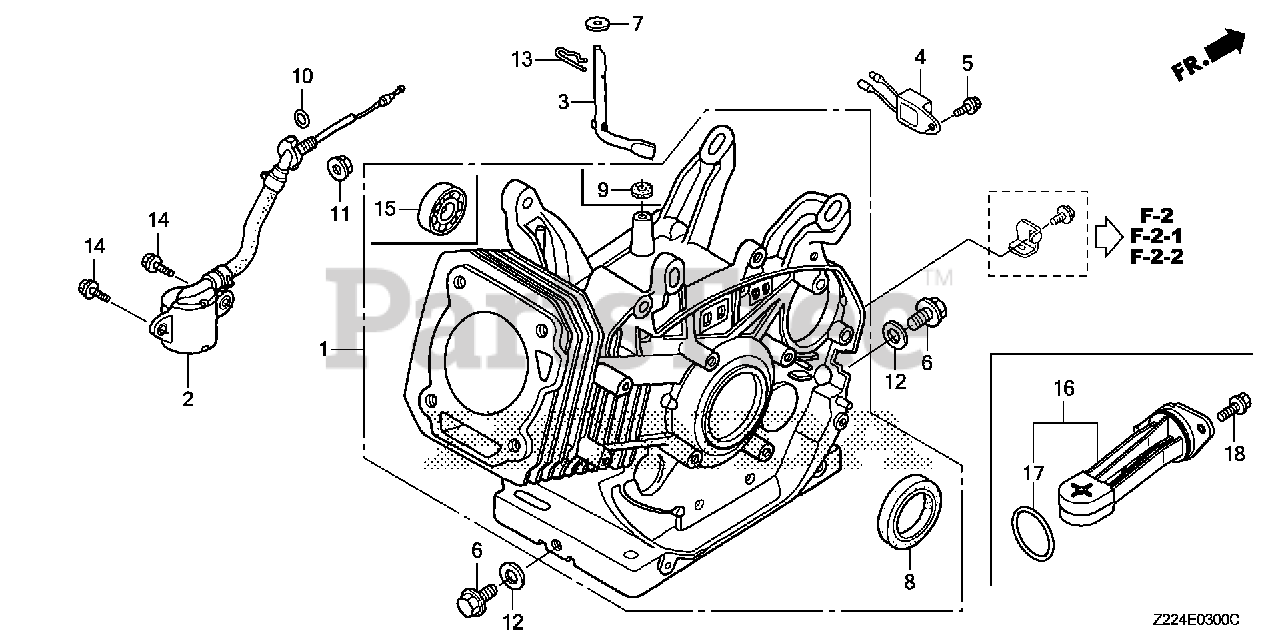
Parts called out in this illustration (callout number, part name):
1	CYLINDER ASSY.
6	BOLT, DRAIN PLUG
8	OIL SEAL (35X52X8) (NOK)
12	WASHER, DRAIN PLUG (12MM)
15	BEARING, RADIAL BALL (6202)
16	SWITCH ASSY., OIL LEVEL
17	O-RING (37.9X2.4)
18	BOLT, FLANGE (6X16)
